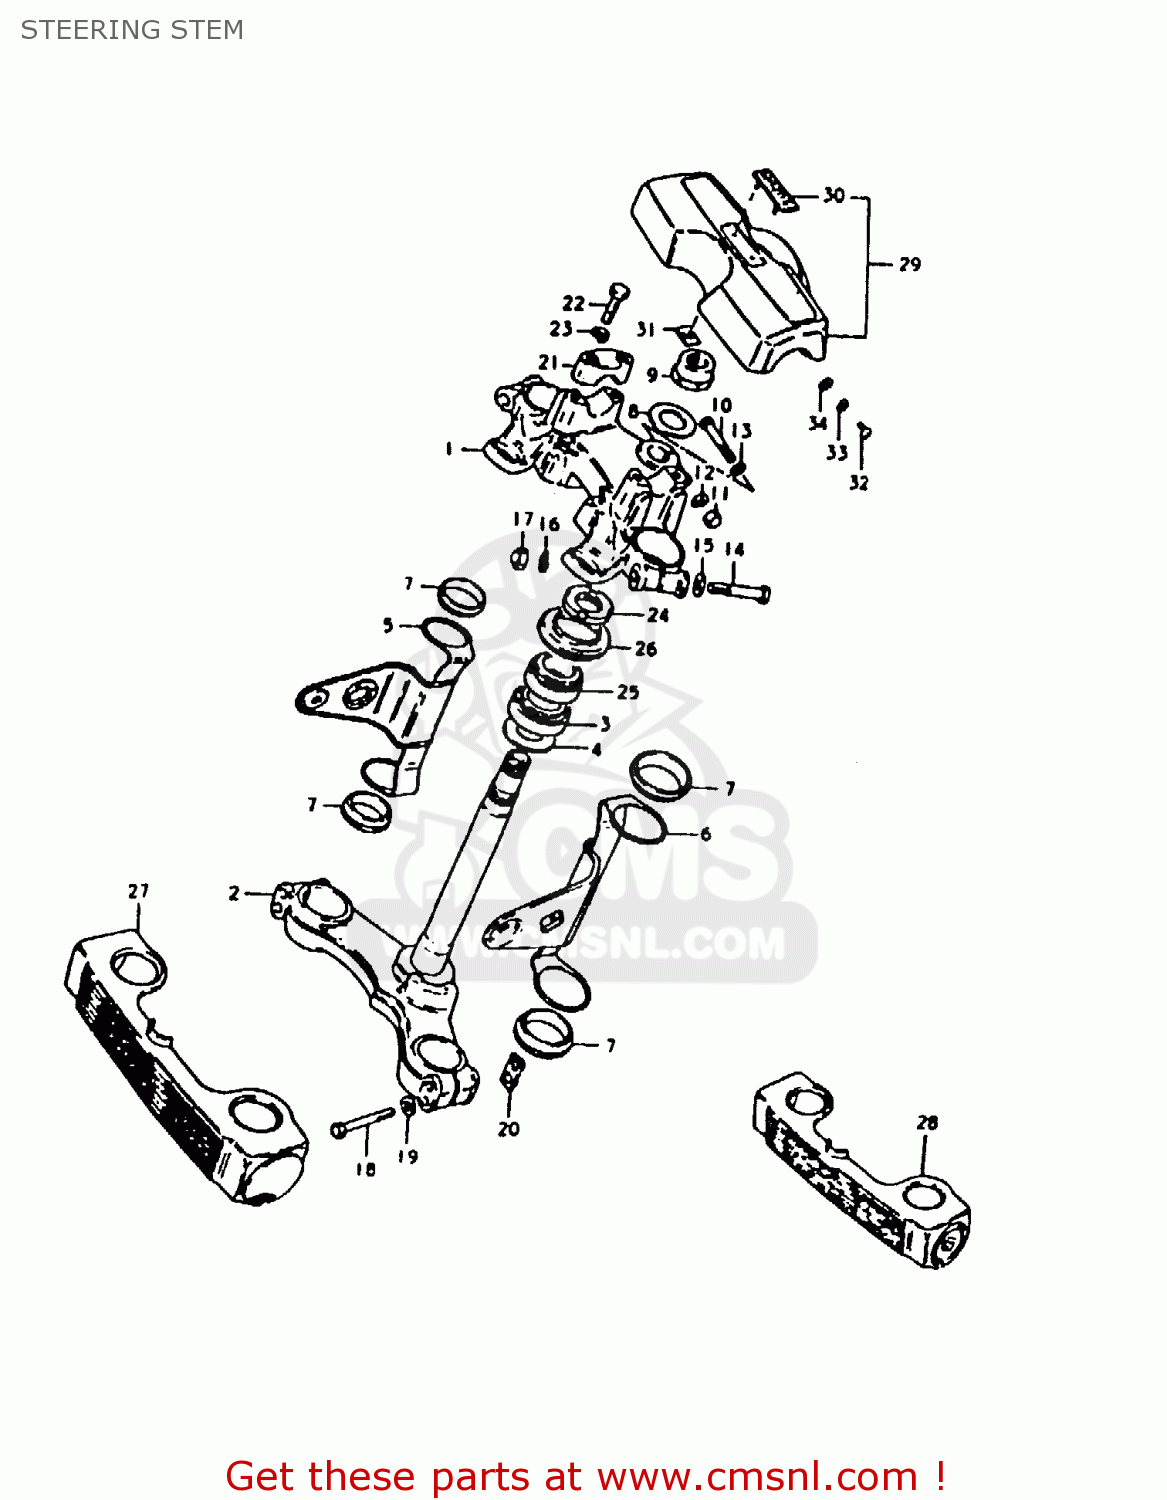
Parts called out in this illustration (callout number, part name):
1	HEAD,STEERING STEM
2	STEM,STEERING
3	BEARING
4	WASHER,THRUST
5	BRACKET,HEADLAMP,RIGHT
6	BRACKET,HEADLAMP,LEFT
7	CUSHION,HEADLAMP BRACKET
8	WASHER
9	NUT,FR FORK UPR BRACKET
10	BOLT 8X50
11	NUT
12	LOCK WASHER
13	WASHER
14	BOLT 10X55
15	WASHER
16	LOCK WASHER
17	NUT, LOWER LH
18	BOLT 8X55
19	WASHER
20	NUT,FR FORK INNER TUBE
21	HOLDER,HANDLE(BLACK)
22	BOLT
23	LOCK WASHER
24	NUT,STEERING STEM(25X44X10)
25	TAPER,ROLLER BEARING
26	DUST SEAL,STEERING,UPPER
27	COVER,FRONT FORK
29	PAD,HANDLEBAR
30	EMBLEM,HANDLE COVER PAD
31	NUT
32	SCREW
33	LOCK WASHER
34	WASHER
